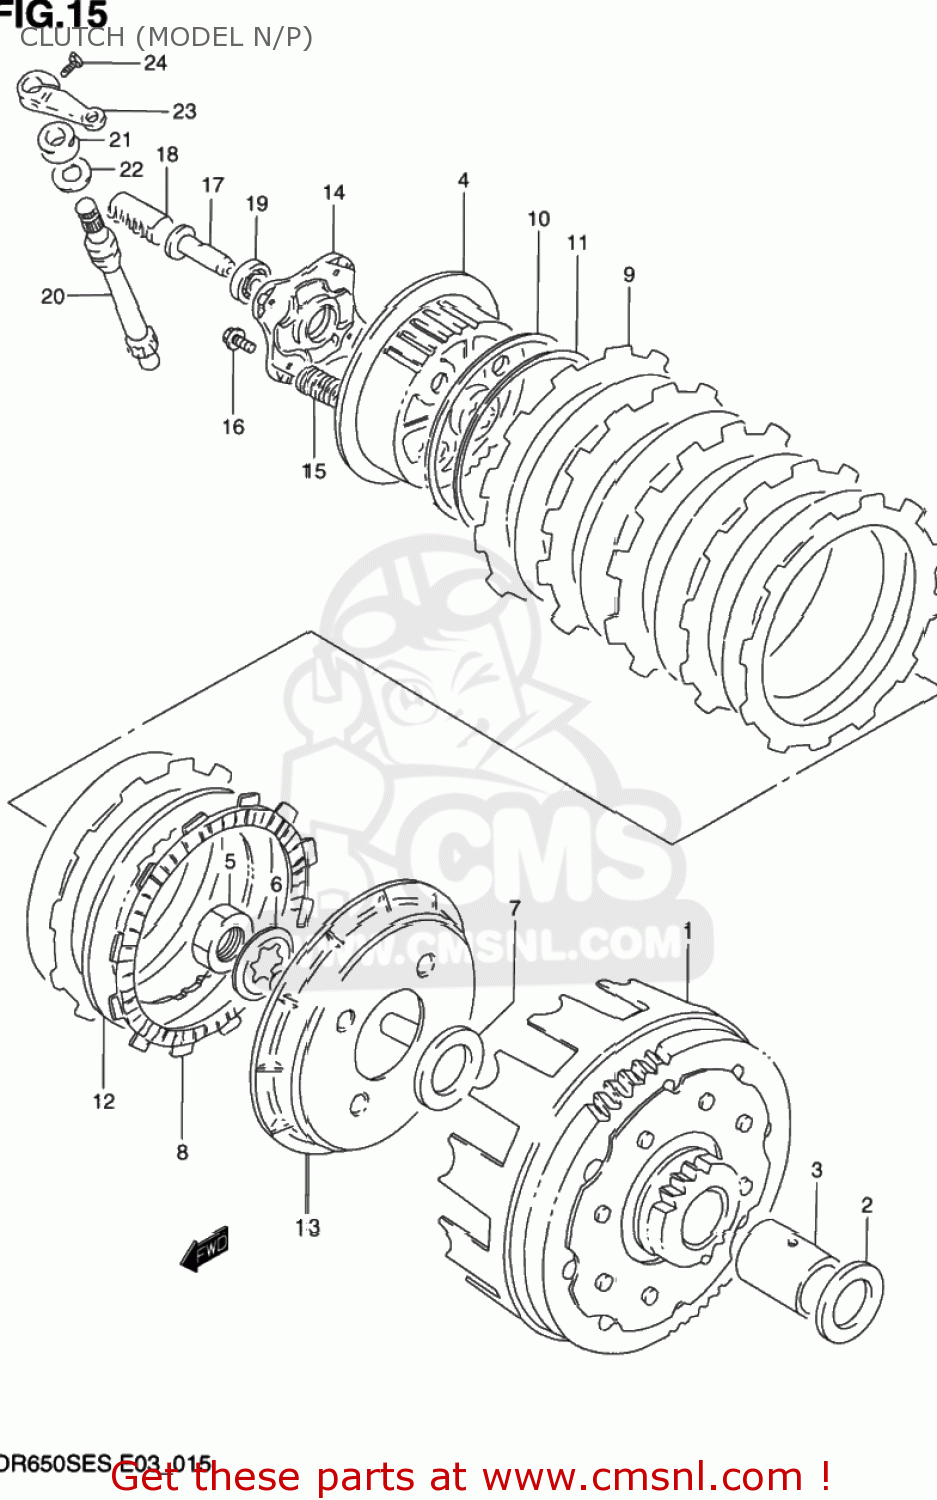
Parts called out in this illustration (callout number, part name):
1	GEAR ASSEMBLY,PRIMARY DRIVE
2	WASHER
3	SPACER(22X28X32.5)
4	HUB,CLUTCH SLEEVE
5	NUT
6	WASHER,LOCK
7	WASHER
8	PLATE,CLUTCH DRIVE (NAS)
9	PLATE,CLUTCH DRIVE NO (NAS)
10	SEAT,WAVE WASHER(T:1.4)
11	WASHER
12	PLATE,CLUTCH DRIVEN (NAS)
13	DISC,CLUTCH PRESSURE
14	PLATE,RELEASE
15	SPRING
16	BOLT 6X20
17	PIECE,CLUTCH PUSH
18	RACK,CLUTCH RELEASE
19	BEARING
20	PINION,CLUTCH RELEASE
21	SEAL,OIL (12X22X9)
22	WASHER (14.2X22X1)
23	ARM,CLUTCH RELEASE
24	BOLT
